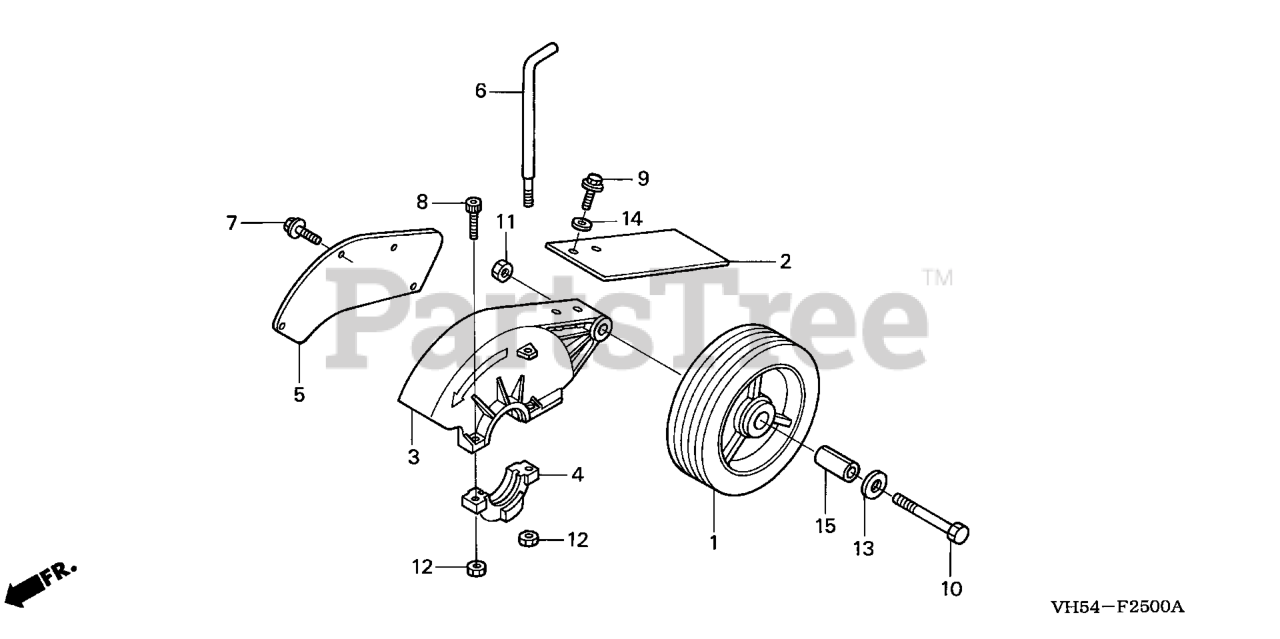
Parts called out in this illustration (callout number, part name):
2	SHIELD, RR.
3	DEFLECTOR, GRASS
4	HOLDER, PROTECTOR
5	PLATE, DEFLECTOR
6	GRIP, HEIGHT ADJUST LEVER
7	SCREW, SELF-TAPPING (8-32X1/2) (NOT AVAILABLE)
8	BOLT, SOCKET (1/4-20X1)
9	BOLT, SELF-TAPPING (10X24X3/4)
10	BOLT, HEX. (5/16-18X2) (3/4)
11	NUT, HEX. (5/16-18)
12	NUT, NYLON INSERT (1/4"-20) (NOT AVAILABLE)
13	WASHER, PLAIN (5/16)
14	WASHER, FLAT (#10)
15	COLLAR, WHEEL
